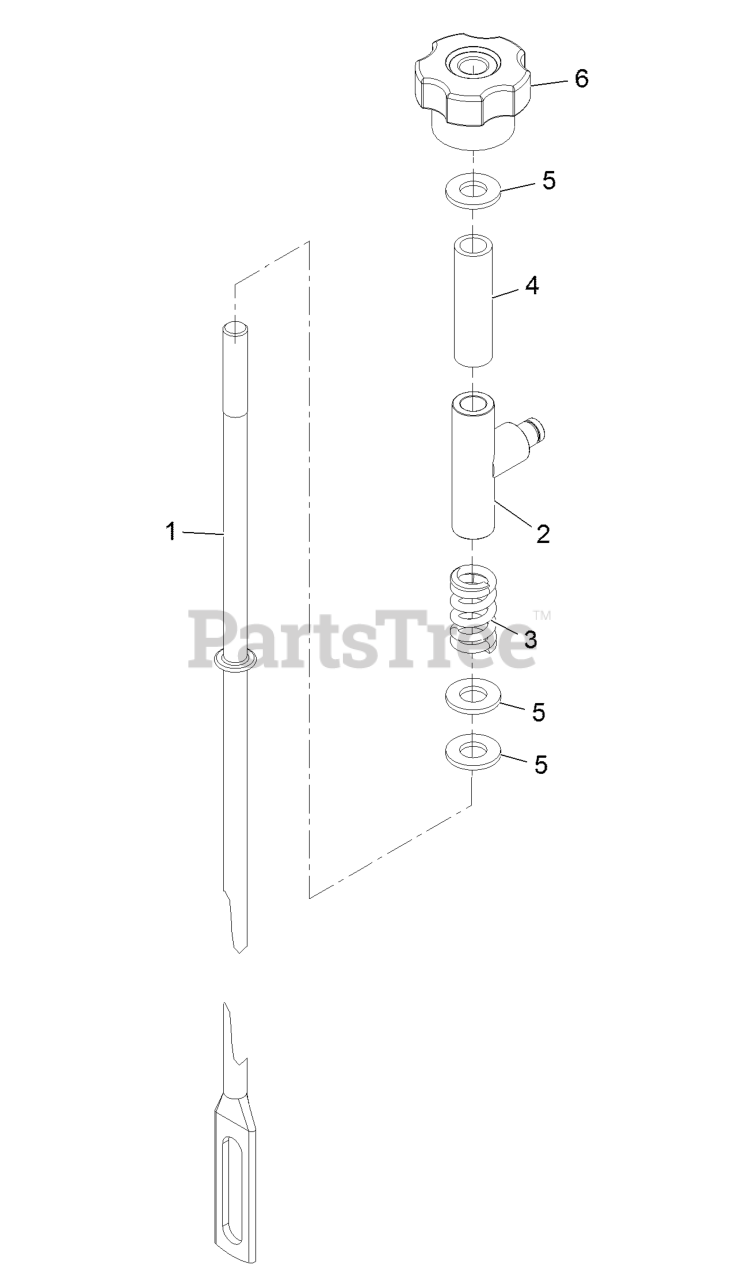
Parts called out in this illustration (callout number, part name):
1	ROD, RIGHT
3	SPRING, COMPRESSION
5	WASHER-FLAT
